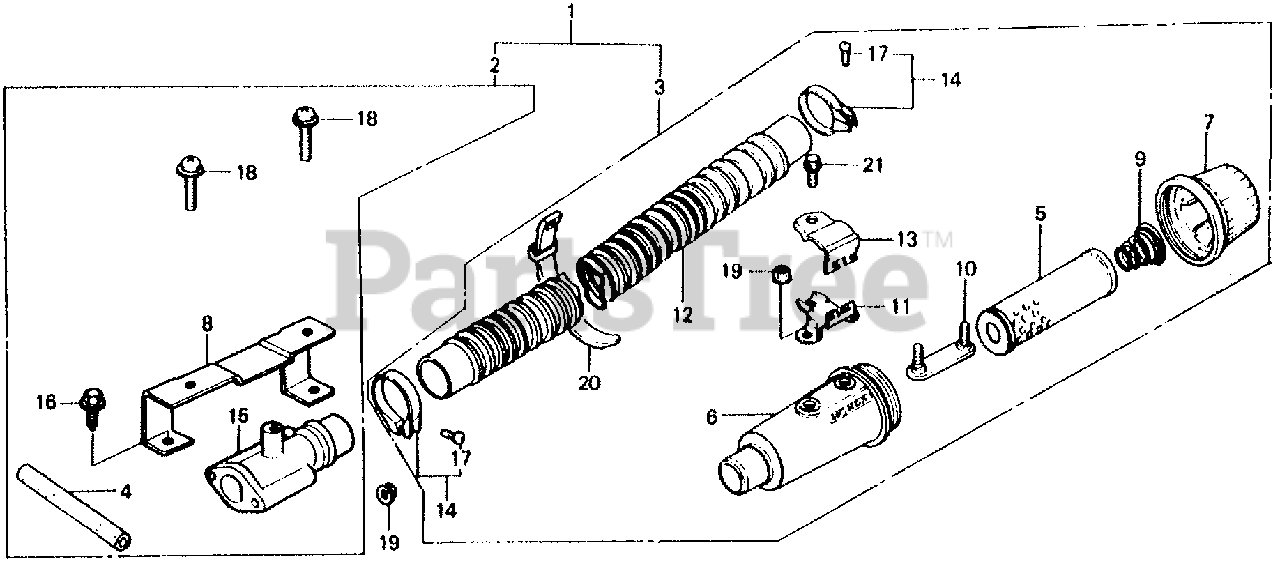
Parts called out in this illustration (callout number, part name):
1	AIR CLEANER KIT, SNORKEL JOINT
2	JOINT KIT, SNORKEL AIR CLEANER (Honda Code 0905729). (N/A: SEE COMPONENTS)
3	AIR CLEANER KIT, SNORKEL
4	TUBE, BREATHER
5	ELEMENT, AIR CLEANER
6	HOUSING, AIR CLEANER
7	CAP, AIR CLEANER
8	STAY, CARBURETOR COVER
9	SPRING, SETTING
10	PLATE, AIR CLEANER SETTING
11	BRACKET A, AIR CLEANER
12	HOSE, AIR CLEANER
13	BRACKET B, AIR CLEANER
14	BAND, AIR CLEANER CONNECTING (Honda Code 0220350). TUBE
14	BAND, AIR CLEANER CONNECTING (Honda Code 5903182). TUBE (34)
15	JOINT, TUBE CONNECTING
16	BOLT, FLANGE (6X12) (CT200)
17	SCREW, PAN (4X25)
18	SCREW-WASHER (6X25) (Honda Code 0802538). (NOT AVAILABLE)
19	NUT, FLANGE (6MM)
20	BAND B3, CABLE HARNESS
21	BOLT, FLANGE (6X16)
